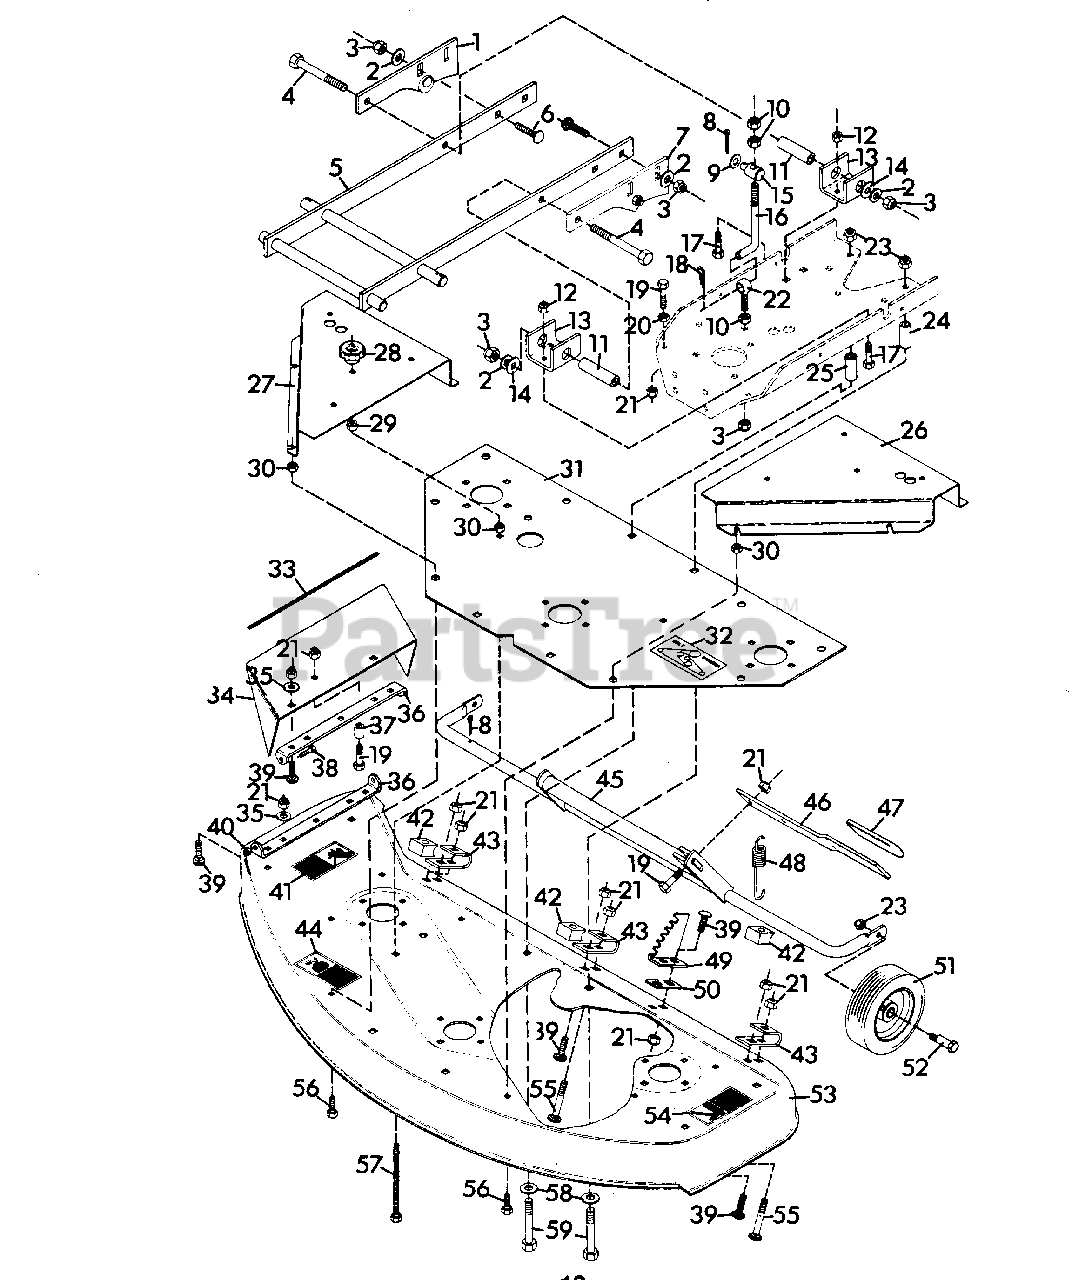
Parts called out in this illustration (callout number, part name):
1	Weldment, Deck Leveling R.H.
2	Washer, Flat .531x1.250x.100
3	Nut, Lock 1/2-13
4	Bolt, Hex 1/2-13x3.25
5	Weldment, Pivot Arm
6	Bolt, Carriage 1/2-13x1.25
7	Weldment, Deck Leveling L.H.
8	Pin, Cotter .125x1.25
9	Washer, Flat .531x1.000x.063
10	Nut, Jam 1/2-13 Hex
11	Bushing, Pivot .510x.750x2.020
12	Nut, Lock 5/16-18
13	Support, Mower Pivot
14	Washer, Flat .813x1.37x.100
15	Pivot, Mower Lift
16	Rod, Lift
17	Bolt, Hex 5/16-18x.875
18	Pin, Cotter Hair
19	Bolt, Hex 3/8-16x1.50
20	Nut, Jam 3/8-16 Hex
21	Nut, Lock 3/8-16
22	Bolt, Eye
23	Nut, Lock 1/2-13
24	Spacer, .510x.840x2.43
25	Spacer
26	Cover, Pulley L.H.
27	Cover, Pulley R.H.
28	Knob
29	Nut, Lock 5/16-18
30	Nut, Jam 5/16-18 Hex
31	Plate, Support
32	Decal, Belt Installation
33	Stripe
34	Chute, 40" Flip-Up
35	Washer, Flat .406x.812x.065
36	Bracket, Chute 40" Mower
37	Stop, Chute
38	Bolt, Hex 1/4-20x.875
39	Bolt, 3/8-16x1 Rd Hd Sq Nk
40	Nut, Lock 1/4-20
41	Decal, Danger Hand
42	Stop, Nylon
43	Bracket, Axle Support
44	Decal, Warning Eye
45	Weldment, Axle Pivot
46	Lever, Height of Cut
47	Grip, Handle
48	Spring, 40 and 50 Inch Mower
49	Bracket, Height Adjust
50	Shim, Mower Ht. Adj. Bkt.
51	Wheel, Gauge
52	Bolt, Eccentric
53	Weldment, 40" Deck
54	Decal, Danger Foot
55	Bolt, 3/8-16x2 Rd Hd Sq Nk
56	Bolt, Hex 5/16-18x.75
57	Bolt, Hex 5/16-18x3.50
58	Washer, Flat .531x1.062x.095
59	Bolt, Hex 1/2-13x3.75
